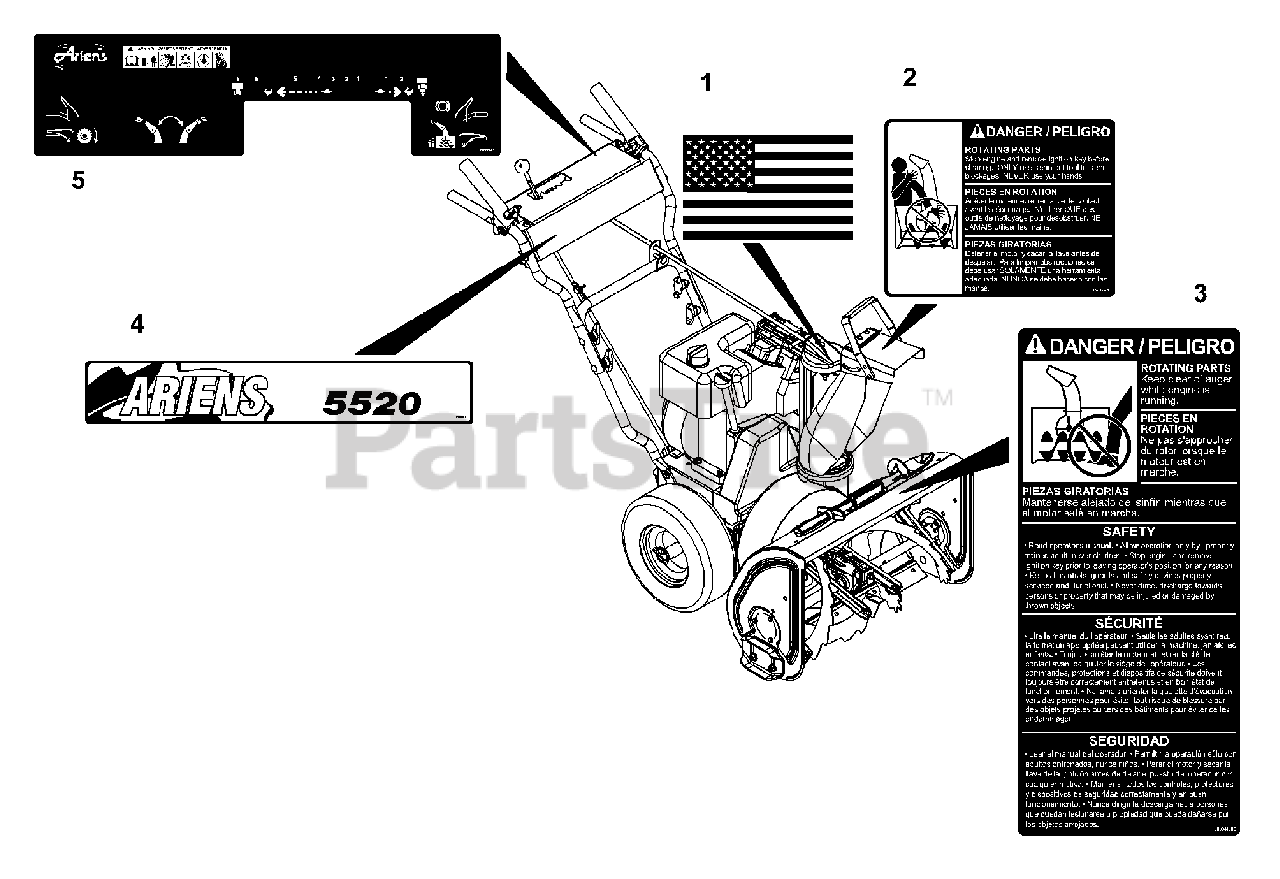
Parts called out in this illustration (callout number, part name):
1	DECAL, AMERICAN FLAG
2	DECAL, DANGER - ROT. PARTS
3	DECAL, DANGER
4	DECAL, FRONT PANEL ST7524
5	DECAL, DASH PANEL - COMPACT
